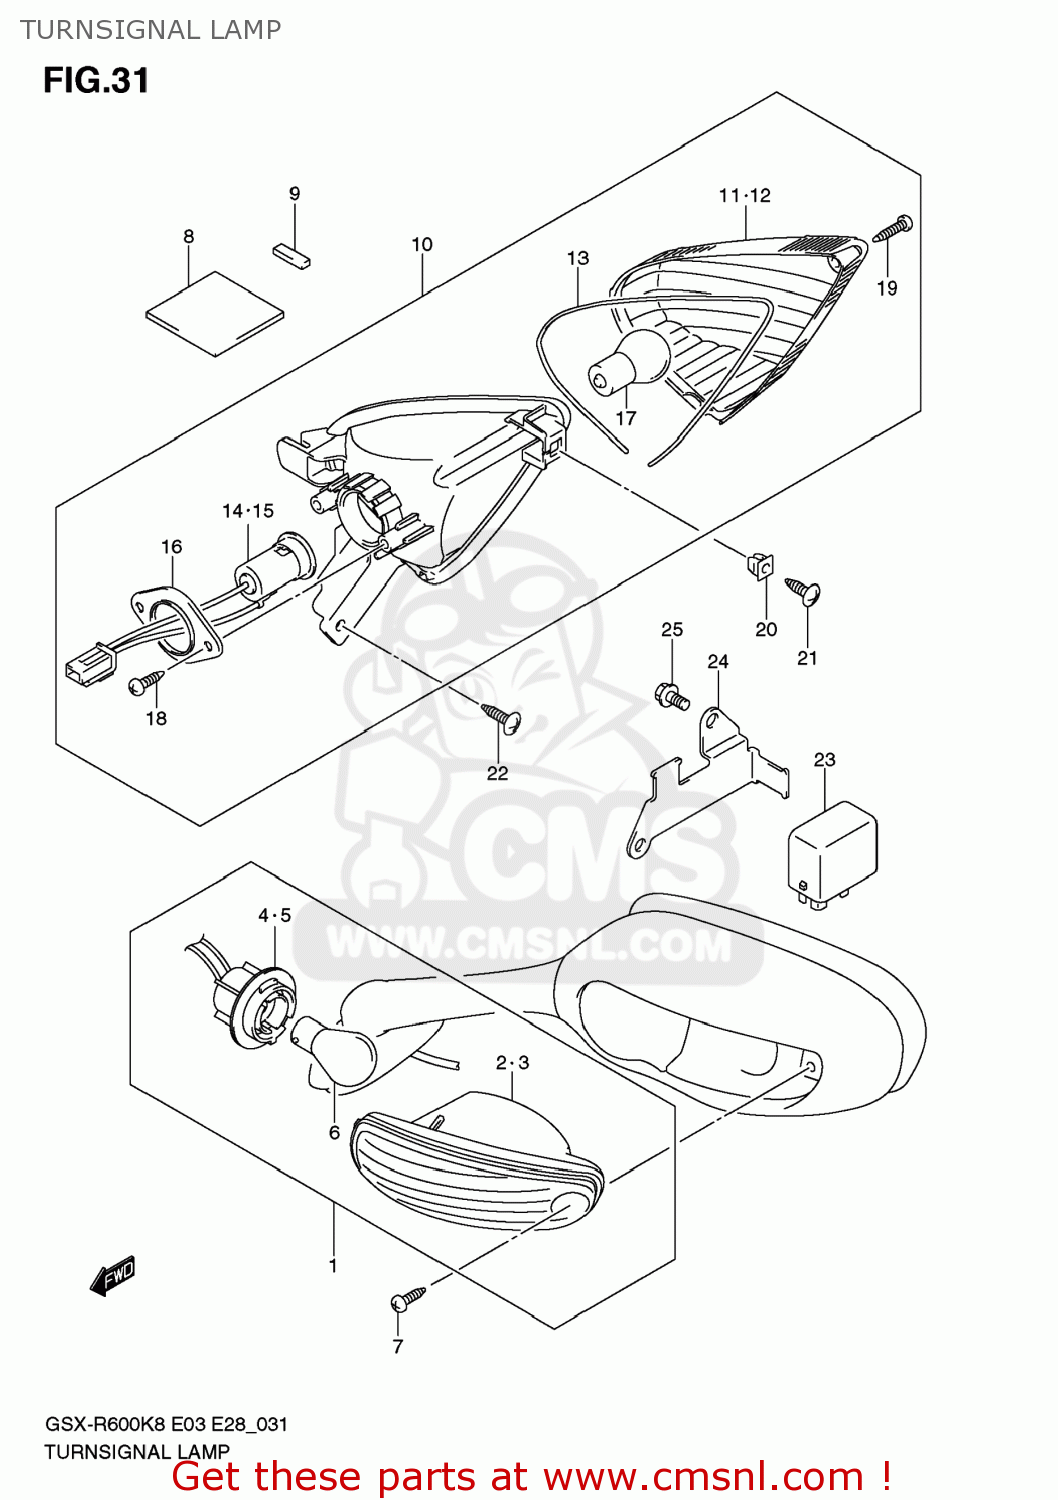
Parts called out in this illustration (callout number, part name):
1	LAMP ASSY,FR TURN SIGNAL,R
2	LAMP UNIT,R
3	LAMP UNIT,L
4	SOCKET,R
5	SOCKET,L
6	BULB(12V21W,AMBER)
7	SCREW(4X20)
8	PROTECTOR(50X50X5)
9	TAPE,FR TURNSIGNAL
10	LAMP ASSY,RR TURNSIGNAL,R
11	LENS,R
12	LENS,L
13	GASKET (NAS)
14	SOCKET & CORD,R
15	SOCKET & CORD,L
16	PLATE,RR COMBINATION
17	BULB(12V21W,AMBER)
18	SCREW
19	SCREW
20	NUT
21	SCREW
22	SCREW
23	RELAY ASSY,TURNSIGNAL LAMP
24	BRACKET,RELAY
25	BOLT
